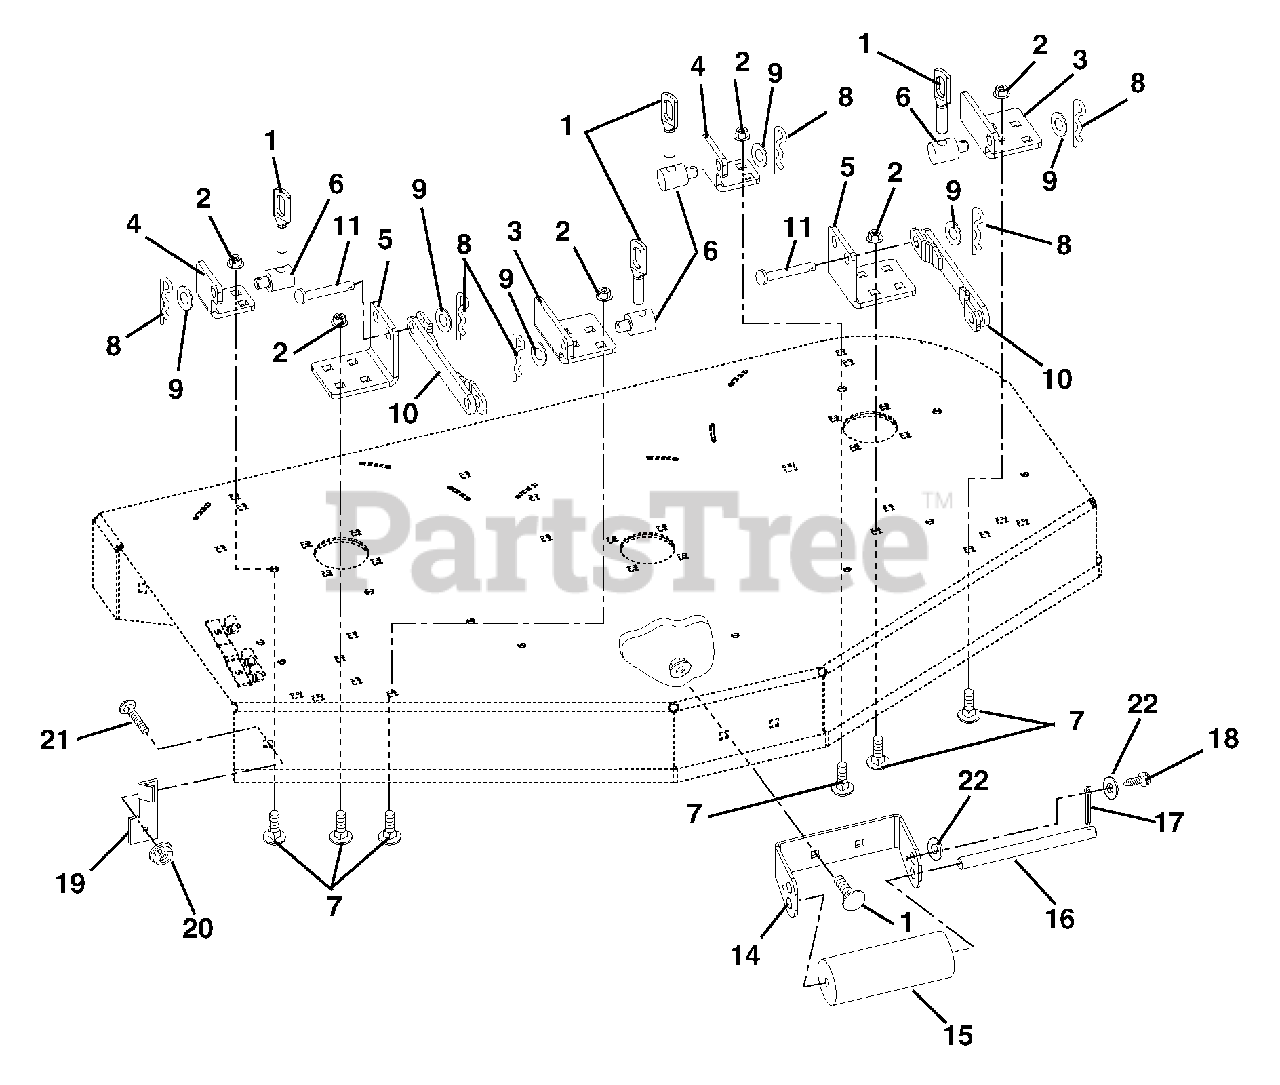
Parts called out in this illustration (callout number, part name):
1	Deck Link
2	Nut .38-16 Flange Nyloc
3	Bracket, Mount, Front
4	Bracket, Rear Mount
5	Bracket, Stabilizer
6	Trunnion
7	Bolt, Round Head Square Neck .38-16 x .75 Grade 5
8	Pin, Hair, External
9	Washer-Flat-STL.511 x 1.441 x .125
10	Weldment, Stabilizer Arm
11	Clevis Pin, .491/.496 x 1.25
12	Nut .38-16 Flange Nyloc
13	Bolt, Round Head Square Neck .38-16 x .75 Grade 5
14	Bracket, Roller Mount
15	Roller
16	Pin, Retainer
17	Pin, Cotter .25 x 1.00
18	Screw, Tapping .25-20 x .50 Hex Washer Head
19	Bracket, Chute Lock
20	Nut-Flange .375-16
21	Bolt, Round Head Square Neck .38-16 x 1.25
22	Washer, Flat Steel .344 x .688 x .06
